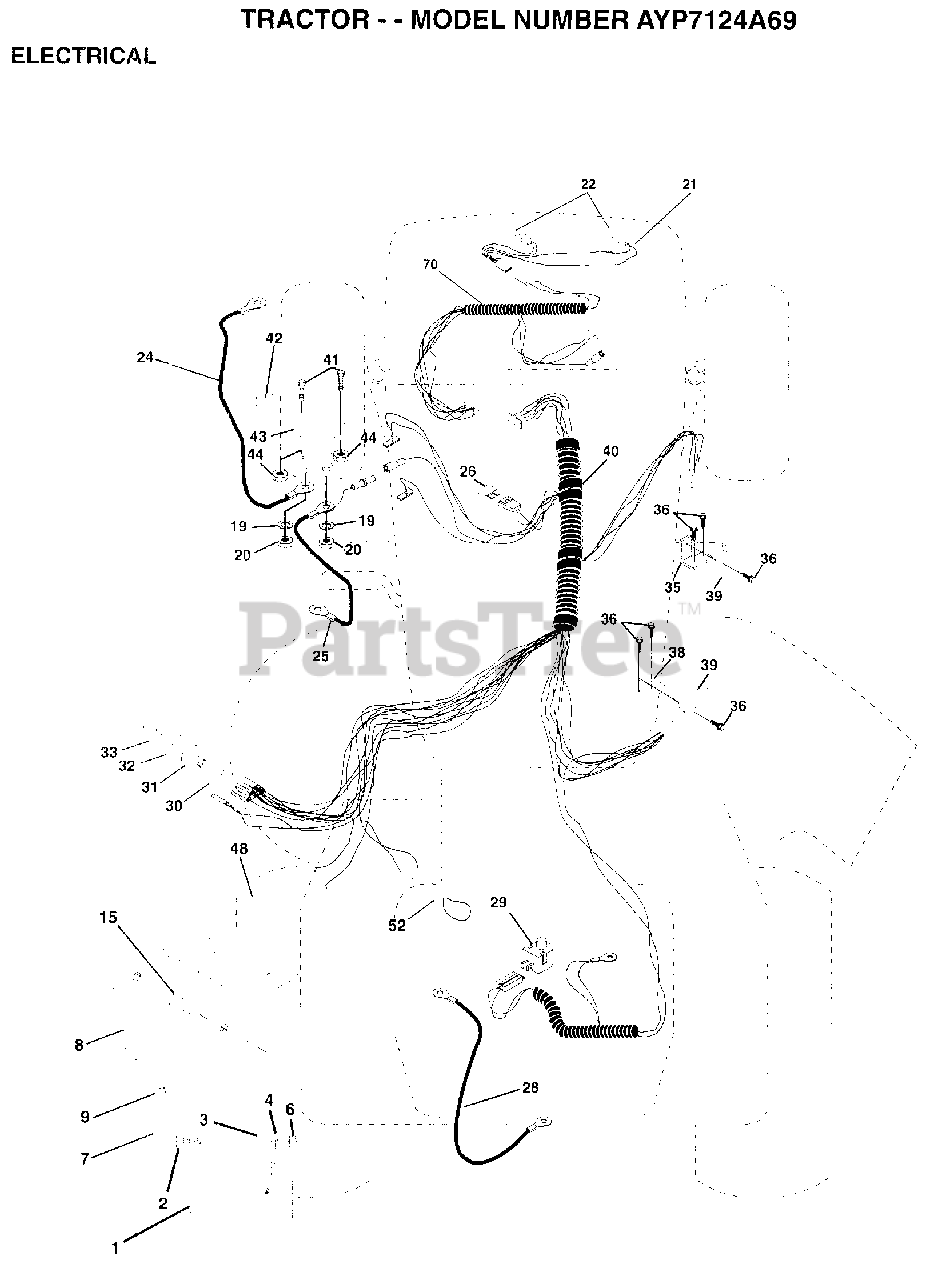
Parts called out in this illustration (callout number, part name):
2	BOLT LT
3	WASHER
7	TUBE T
9	HOSE CLAMP T
15	FASTNER.SNAP-IN
20	NUT
21	"HARNESS,LIGHT SOC"
22	HEADLAMP BULB
24	"CABLE T, BATTERY"
25	CABLE.BTRY.6GA.RD
26	FUSE HYT
28	CABLE T
29	SWITCH SEAT
30	SWITCH IGN 4POS
31	NUT IGNITION
32	COVER KEY SWITCH
33	KEY
35	BRACKET LT
36	SCREW
38	BRACKET SWITCH IN
39	SWITCH INTERLOCKT
40	HARNESS.IGNITION
41	BOLT.HX.1/4-20
44	NUT HXKEP 1/4X20
46	PROTECTION LOOP
48	ADAPTER AMMETER
52	PROTECTION LOOP
70	HARNESS.ENGINE
